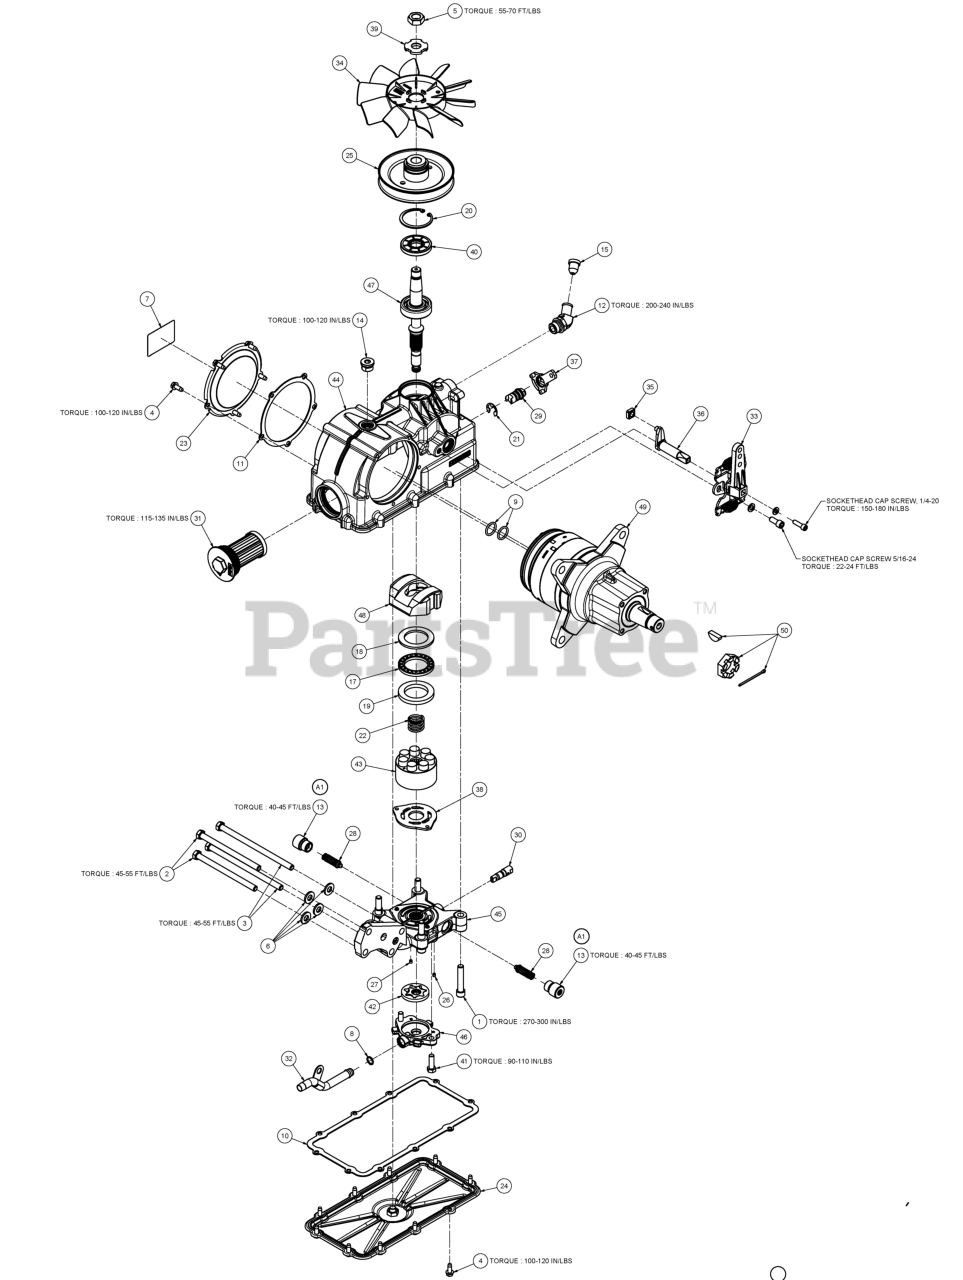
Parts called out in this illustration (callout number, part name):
5	NUT CHART
6	FLAT WASHER
7	LABEL
8	PACKING PREFORMED O-RING SEAL
9	PACKING PREFORMED O-RING SEAL
10	GASKET BOTTOM COVER FE
11	GASKET SIDE COVER
12	FITTING, 45° BEADED HOSE BARB (SAE STE THD 3/4-16)
13	PLUG & O-RING ASSEMBLY
14	HOLLOW HEX VENT PLUG ASSEMBLY
15	PLUG, RUBBER
17	THRUST BEARING
19	WASHER, THRUST
20	INTERNAL RETAINING RING (SHAFT SEAL)
21	RETAINING RING
22	SPRING (CENTRAL)
23	SIDE COVER
24	SA, BOTTOM COVER
25	PULLEY, TAPERED
26	ORIFICE PLUG (Ø .031)
28	RELIEF VALVE SUB-ASSEMBLY
29	SA, BYPASS
30	S/A, CHARGE RELIEF
31	TRANSMISSION OIL FILTER
32	FILTER TUBE (RH)
33	SN, RTN (RH) STANDARD SPRING
34	FAN KIT
35	CONTROL BLOCK
36	TRUNNION ARM, MACHINED
38	PORT PLATE
39	SPACER,FAN
40	SEAL, SHAFT
41	SCREW, HEX HEAD UNRF
42	ROTOR SET ASSEMBLY
44	TOP HOUSING ASSEMBLY
45	END BLOCK ASSEMBLY (RH)
46	COVER - CHARGE PUMP
47	SA, SHAFT
48	SA, SWASH BLOCK
49	SA, MOTOR
50	SERVICE KIT NUT, COTTER PIN & KEY
